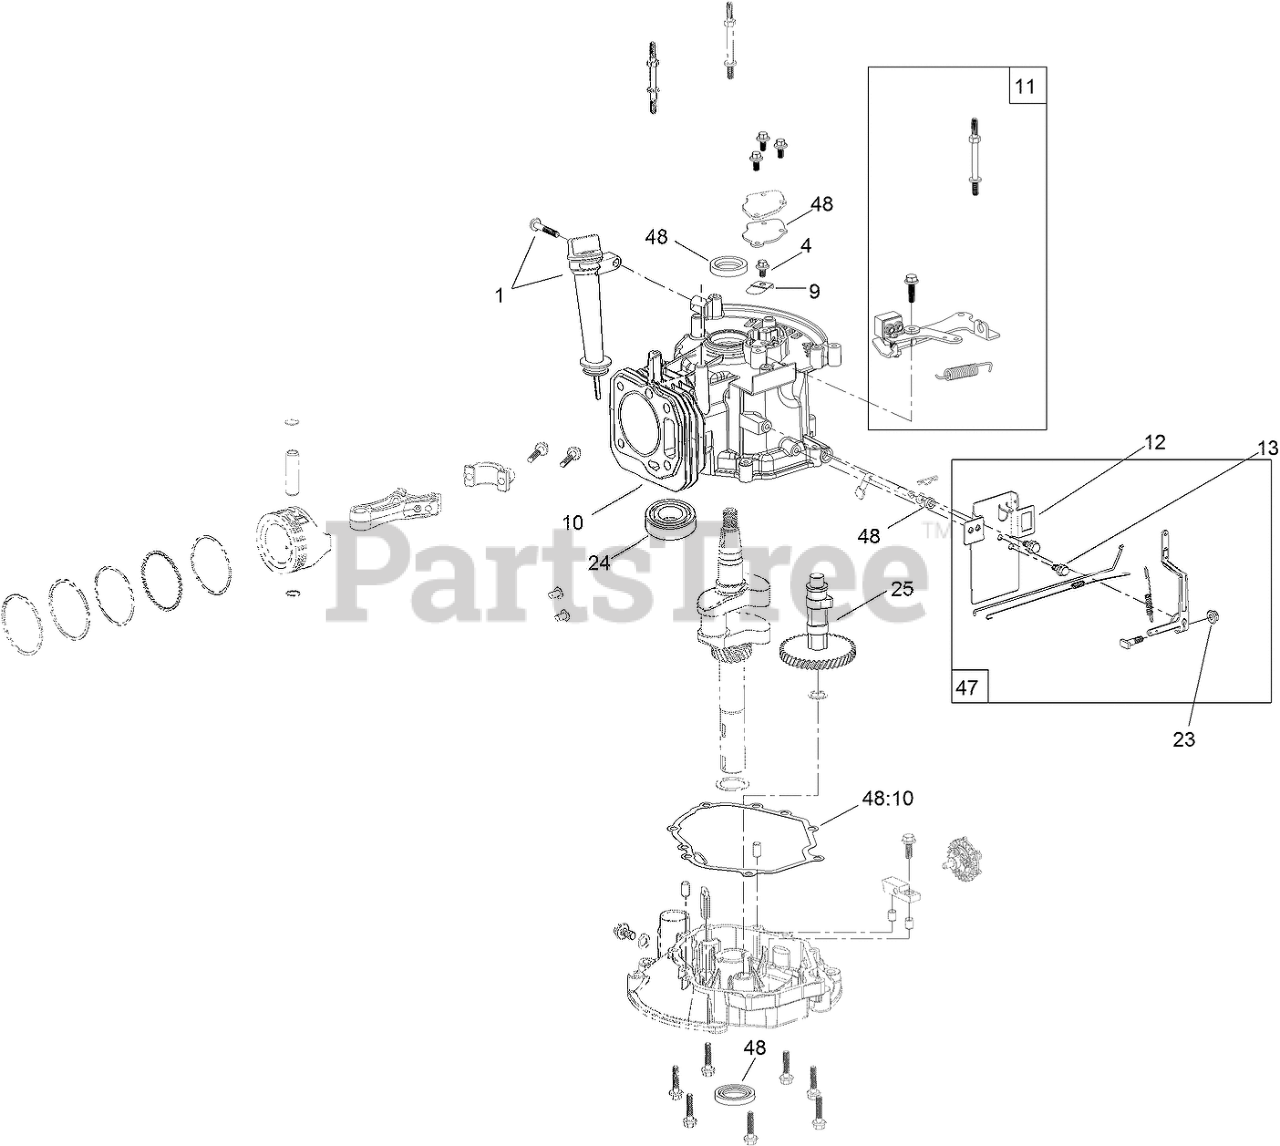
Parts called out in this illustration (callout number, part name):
1	DIPSTICK AND FILL TUBE KIT
4	SCREW-HHF
9	VALVE-REED
10	CRANKCASE
11	BRAKE ASM RECOIL KIT
12	CONTROL ASM
13	SCREW-HHF
23	NUT-FLANGE
24	BEARING-BALL
25	CAMSHAFT ASM
47	GOVERNOR ARM KIT
48	SEAL AND GASKET KIT
48:10	GASKET-VALVE COVER
